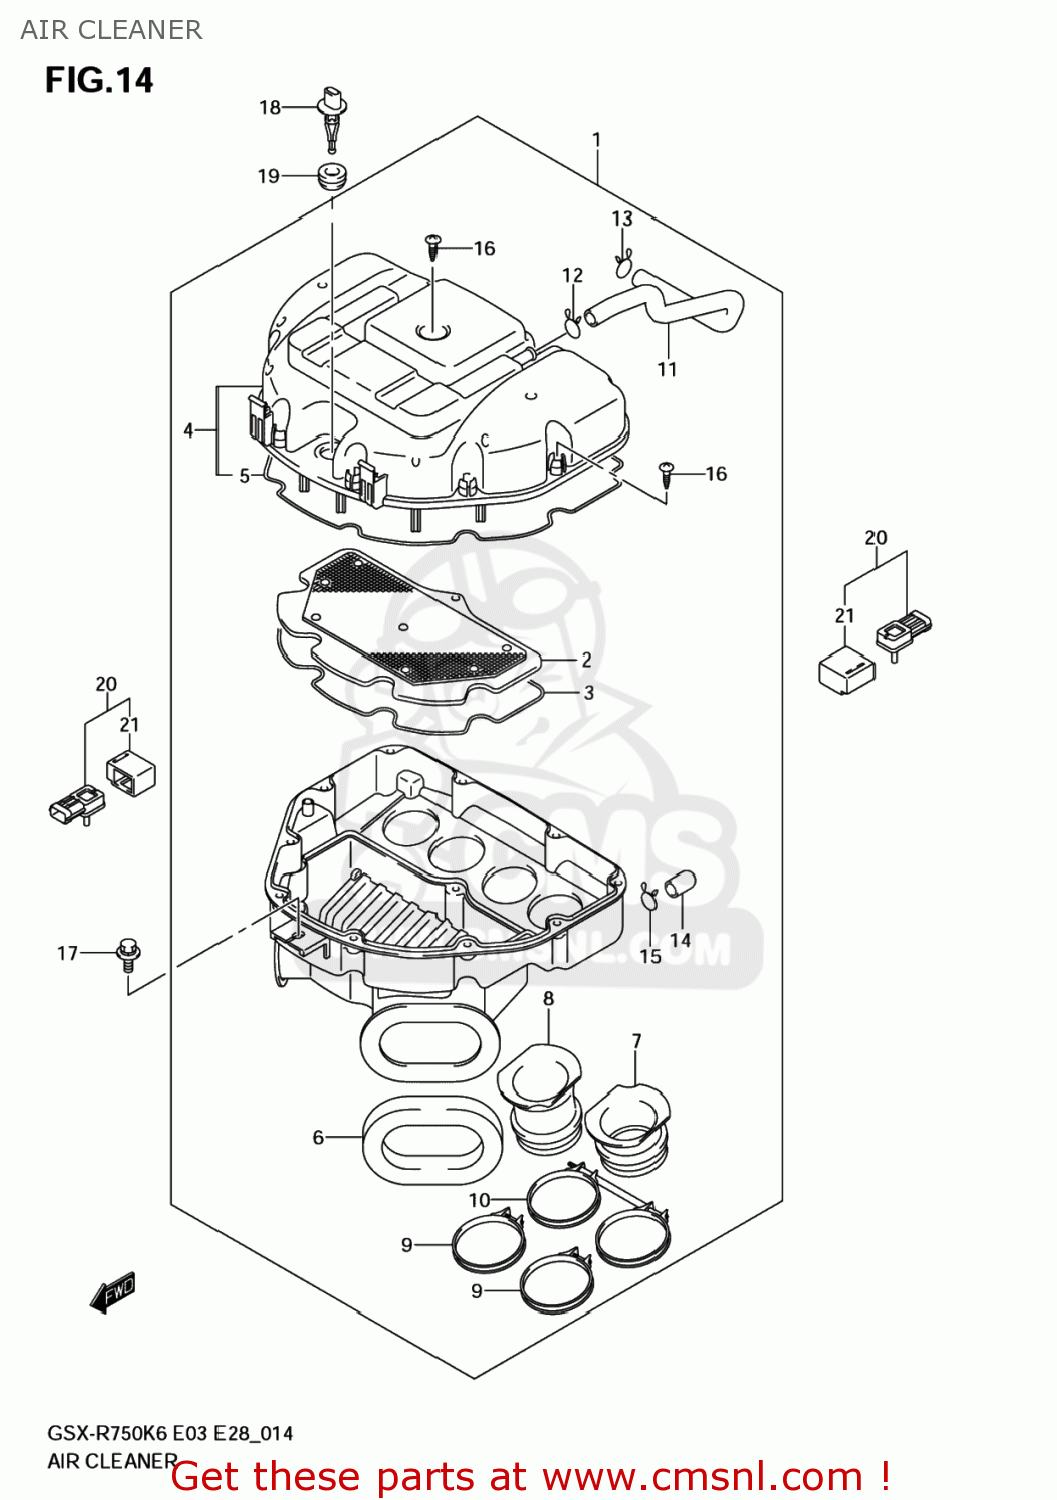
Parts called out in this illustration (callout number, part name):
1	CLEANER ASSY,AI
2	FILTER ASSY
3	GASKET,CASE (NAS)
4	CAP,AIR CLEANER
5	GASKET,CAP (NAS)
6	CUSHION,DUCT
7	TUBE,OUTLET
8	TUBE,OUTLET
9	CLAMP
10	CLAMP
11	TUBE,BREATHER
12	CLIP
13	CLIP
14	PLUG
15	CLIP
16	SCREW
17	BOLT (6X16)
18	SENSOR,INLET AIR TEMP
19	GROMMET,AIR TEMP SENSOR
20	SENSOR,AIR PRESSURE
21	COVER
